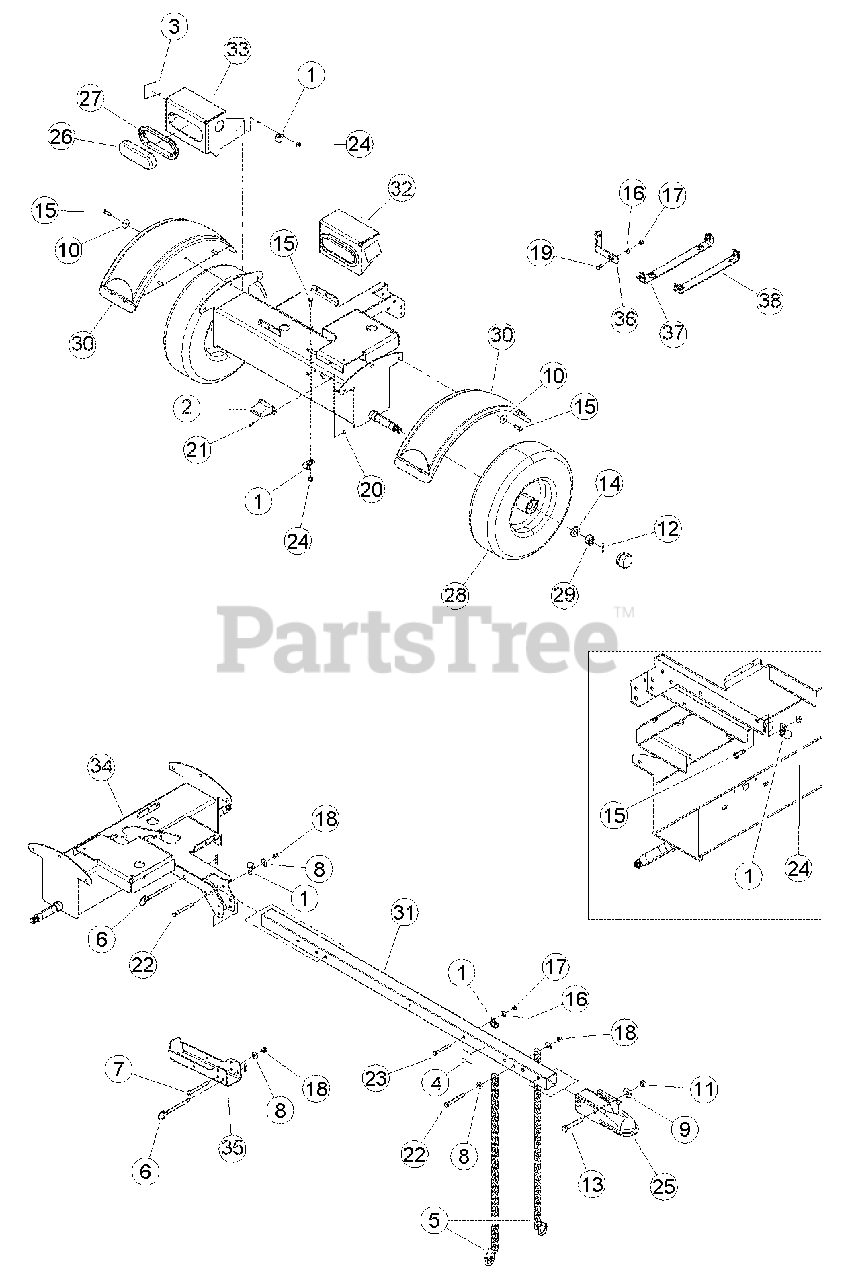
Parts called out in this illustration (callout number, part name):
1	CLAMP, 9/16 COATED
2	LIGHT, LICENSE PLATE
3	REFLECTOR, WIDE ANGLE RED
4	REFLECTOR, WIDE ANGLE AMBER
5	CHAIN, SAFETY 5000 LB W/LATCH
6	PIN, 3/8 HITCH
7	BOLT, 3/8 X 3-1/2 HEX HD GR5 ZP
8	WASHER, 3/8 FLAT ZP
9	WASHER, 1/2 FLAT ZP
10	WASHER, 5/16 FENDER ZP
11	NUT, 1/2 CENTERLOCK GRB ZP
12	PIN, 5/32 X 1-1/4 COTTER ZP
13	BOLT, 1/2 X 3 HEX HD GR5 ZP
14	WASHER, 3/4 SAE FLAT ZP
15	BOLT, 5/16 X 1 HEX HD GR5 NC ZP
16	WASHER, 5/16 FLAT ZP
17	NUT, 5/16 NE NYLOCK ZP
18	NUT, 3/8 NE NYLOCK ZP
19	BOLT, 5/16 X 7/8 HEX HD GR5 NC ZP
20	NUT, 10/24 NYLOCK TYPE NM ZP
21	MACH. SCREW, #10-24 X 3/4 PAN HD PH ZP
22	BOLT, 3/8 X 3-1/4 HEX HD GR5 ZP
23	BOLT, 5/16 X 2-3/4 HEX HD GR5
24	NUT, 5/16 FLANGE TOPLOCK
25	TRAILER HITCH COUPLER
26	TAIL LIGHT, OVAL LED
27	GROMMET, OVAL TAIL LIGHT
28	ASSEMBLY, TIRE 4.8-8
29	NUT, SLOTTED 3/4-16 GRADE 2
30	FENDER, BLACK PLASTIC DRILLED
31	TUBING, HITCH POLE
32	BRACKET, TAIL LIGHT - RH
33	BRACKET, TAIL LIGHT - LH
34	WELDMENT, SC 3" TRAILER
35	STAND, JACK
36	BRACKET, CORNER
37	BRACKET, ENGINE BASE
38	BRACKET, ENGINE BASE
